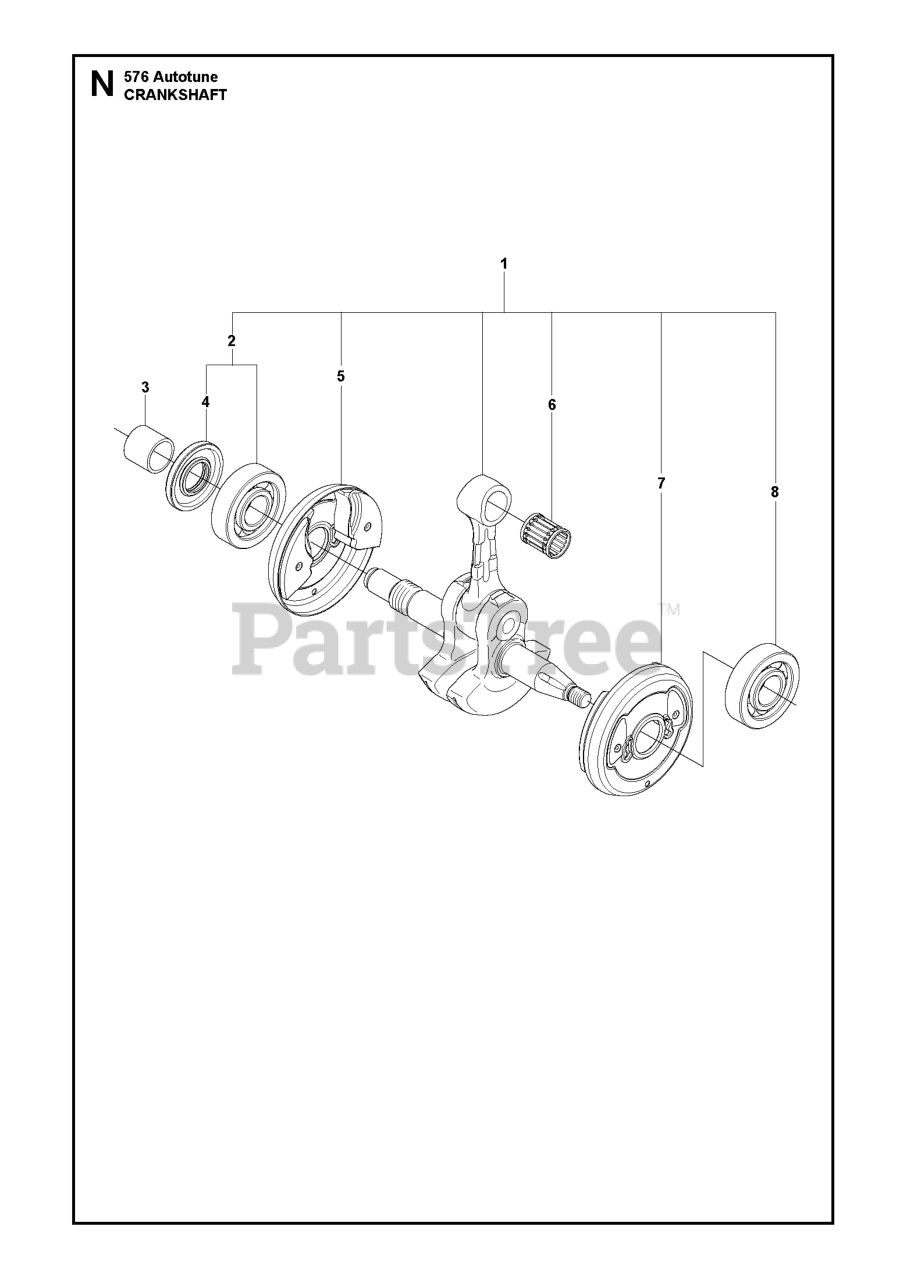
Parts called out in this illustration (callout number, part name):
1	CRANKSHAFT ASSY
2	BALL BEARING
4	RADIAL SEAL
6	NEEDLE BEARING PISTON PIN 12X1
8	BALL BEARING
